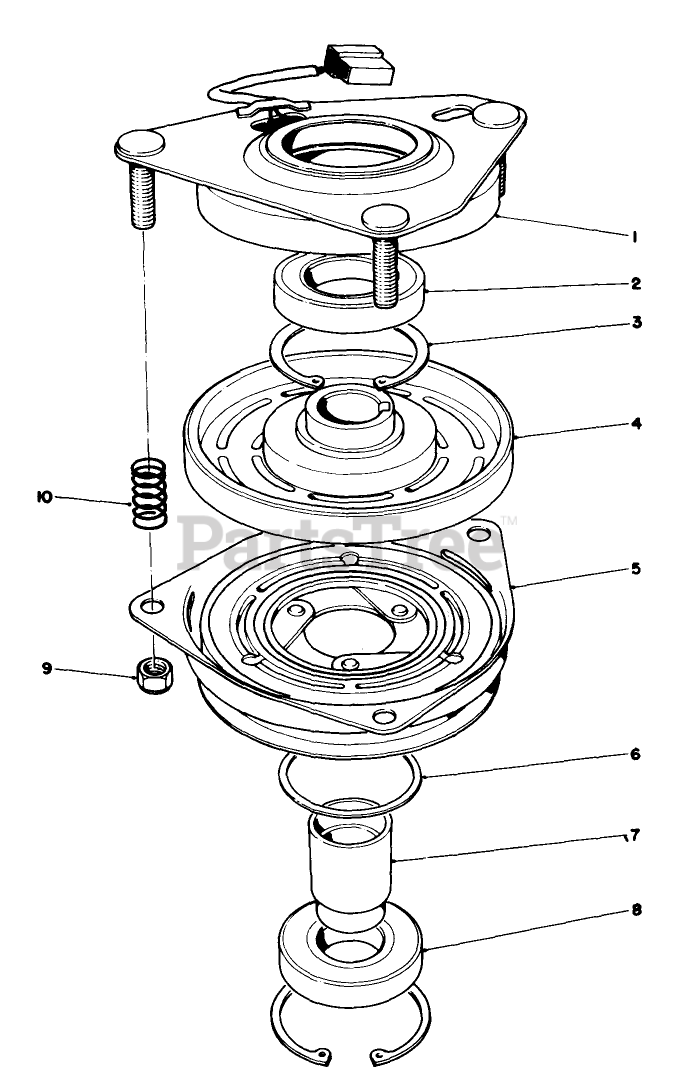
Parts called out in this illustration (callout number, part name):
1	Field Assy (Incl. Ref. #2 & 3)
2	BEARING-FIELD
3	RING-RETAINING
4	Field Coil-Rotor & Bearing Assembly (Incl. Ref. #1)
5	Armature & Pulley Assembly (Incl. Ref. #3, 6, 7 & 8)
6	SPACER-BEARING, PULLEY
7	COLLAR-BEARING
8	BEARING-PULLEY
9	NUT-LOCK
10	SPRING
